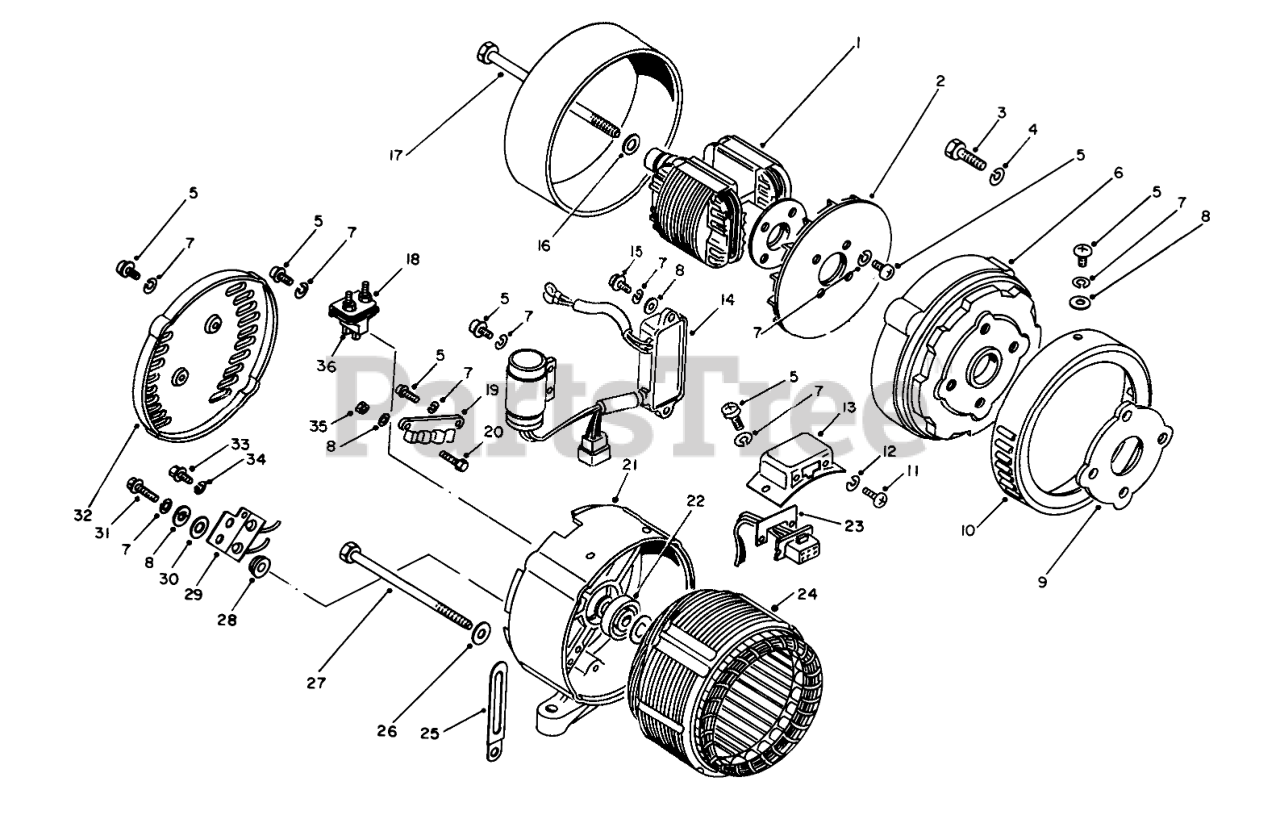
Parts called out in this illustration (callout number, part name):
1	Rotor
4	Lockwasher
5	SCREW
6	Generator Assy. (Incl.Ref.#1,2,5,7,16,17,21,22&24)
7	WASHER
8	WASHER
10	Cover-Front
11	SCREW
12	Lockwasher
13	COUPLER COVER
14	Voltage Regulator
15	Screw
16	Washer
18	Holder
19	Terminal
21	Rear Bracket
22	Bearing
23	Plate
25	Clamp
26	Washer
28	Brush
29	DIODE
30	Washer
31	Screw
34	Lockwasher
36	BRUSH
